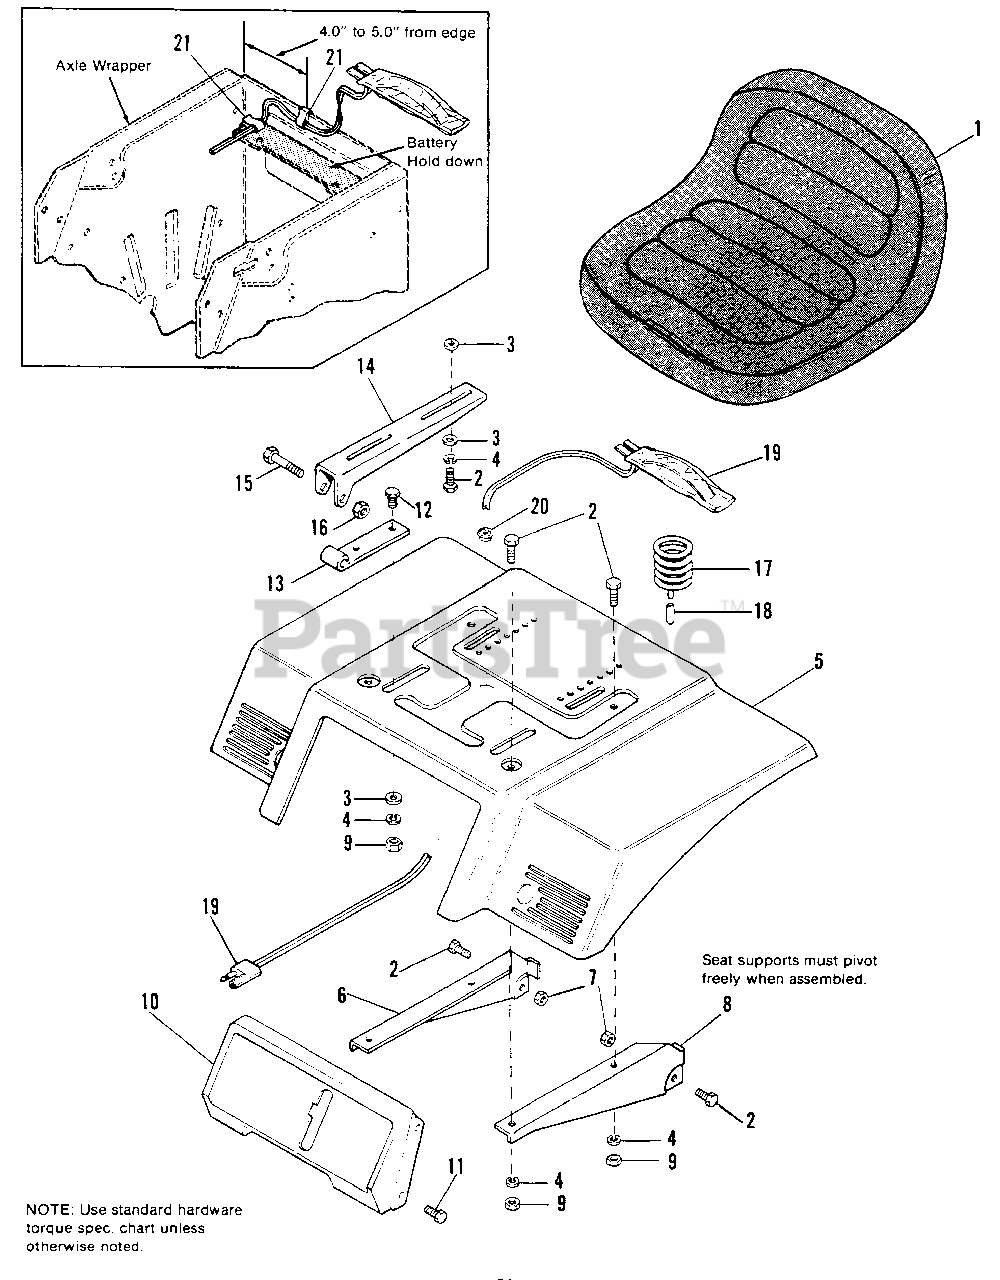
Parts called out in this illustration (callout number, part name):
1	SEAT
1	SEAT (1690995 only)
2	CAPSCREW, 5/16-18 x 3/4
3	WASHER, 5/16 (Qty. 4 on 1690995)
4	LOCKWASHER, 5/16 (Qty. 8 on 1690995)
5	DECK, Seat
6	SUPPORT, Seat, R.H.
7	NUT, Hex, 5/16-18
8	SUPPORT, Seat, L.H.
9	NUT, Hex, 5/16-18 (Qty. 4 on 1690995)
10	PANEL, Shift
11	SCREW, Taptite, 1/4-20 x 1/2
12	CAPSCREW, Hex, 5/16-18 x 1
13	HINGE, Lower
14	HINGE, Upper
15	CAPSCREW, Hex Hd., 3/8-16 x 2
16	NUT, Hex Lock, 3/8-16
17	SPRING, Seat
18	COVER, Wire
19	SWITCH, Seat
20	BUSHING, Universal
21	CLIP
